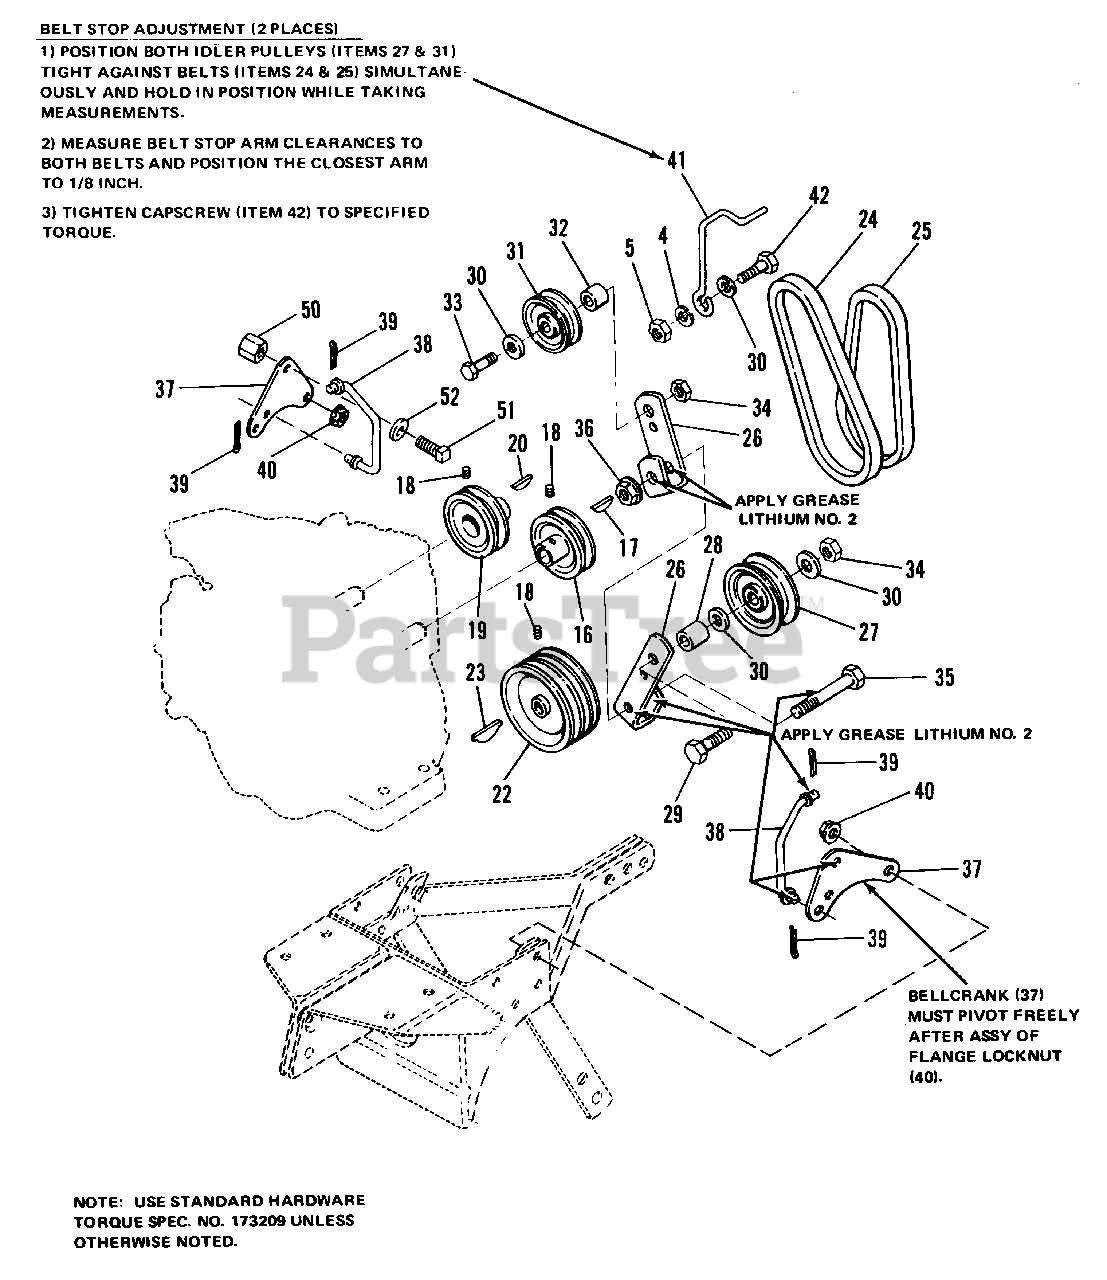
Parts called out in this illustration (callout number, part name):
1	FRAME ASSY
2	STOP, Plate
3	CAPSCREW, Hex, 3/8-16 x 1-1/2
4	LOCKWASHER, 3/8
5	NUT, Hex, Full, 3/8-16
6	WHEEL & TIRE ASSY
7	CAPSCREW, 1/2-13 x 3-1/2
8	WASHER, Plain, 1/2
9	NUT, Hex, Jam, 1/2-13
12	CAPSCREW, Hex, 5/16-18 x 1-3/4
13	LOCKWASHER, 7/16
14	DECAL, Simplicity
15	NUT, Hex, 5/16-18
16	PULLEY, Engine, Forward
17	KEY, Sq., 3/16 x 1
18	SCREW, Set, 5/16-18 x 5/16
19	PULLEY, Engine, Rev.
20	KEY, 1/8 x 5/8, No. 5
21	NUT, Hex, Full, 7/16
22	PULLEY, Drive
24	V-BELT, Reverse
25	BELT, Forward
26	LEVER, Idler Pulley
29	CAPSCREW, Hex, 3/8-16 x 1-3/4
30	WASHER, Plain, 5/16
31	PULLEY, Idler
33	CAPSCREW, Hex, 3/8-16 x 1-1/4
34	LOCKNUT, Hex, Jam, 3/8-16
35	BOLT, Pivot
36	LOCKNUT, Flange, Whiz, 5/16-18
37	BELLCRANK
38	LINK, Rod
39	PIN, Cotter, 1/16 x 3/4
40	LOCKNUT, Hex, Flange, 5/16-18
41	STOP, Belt
42	CAPSCREW, Hex, 3/8-16 x 1
43	COVER, Engine
44	SCREW, Taptite, 1/4-20 x 3/8
45	DECAL, 1005
46	DECAL, Roticul, R.H.
47	DECAL, Roticul, L.H.
48	CAPSCREW, Hex, 3/8-16 x 3/4
49	CAPSCREW, Hex, 7/16-20 x 1-1/4
50	CLAMP, Wire
51	SCREW, Set, No. 10-24 x 5/8
52	WASHER, Plain, 3/16
53	I.D. PLATE
54	LOCKWASHER, Spring, 5/16
